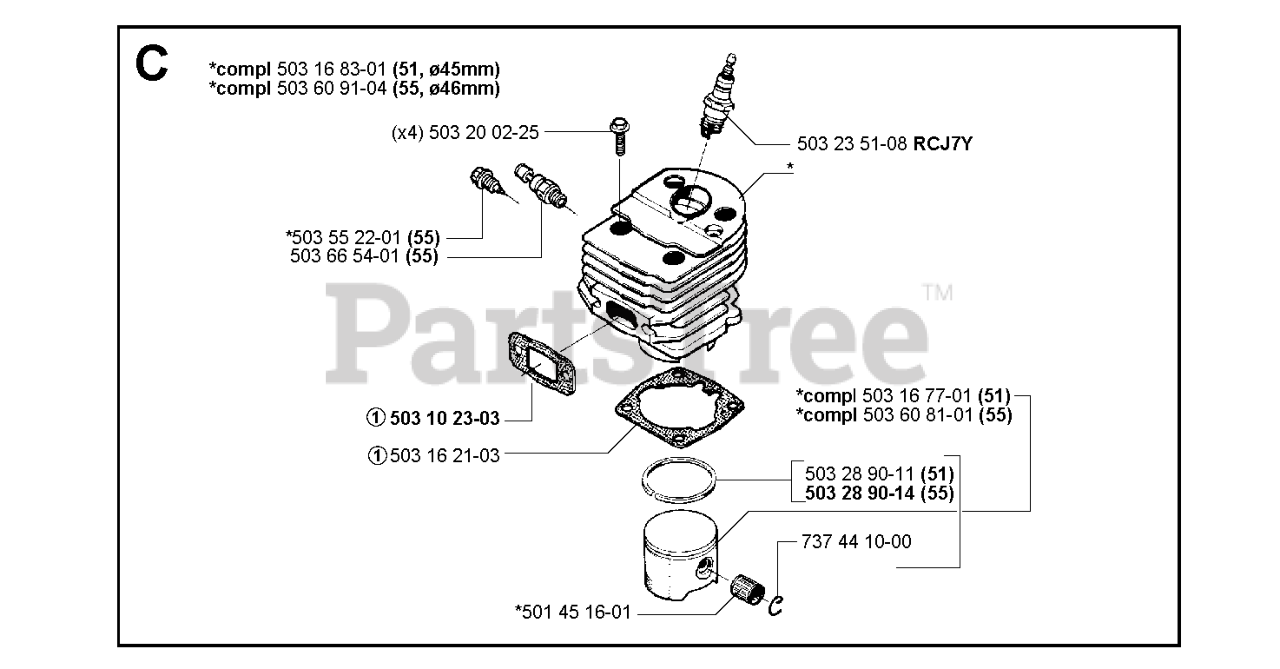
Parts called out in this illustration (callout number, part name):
296	Studs
304	Housings
305	Screws
613	Screws
968	Covers
1193	Screws
